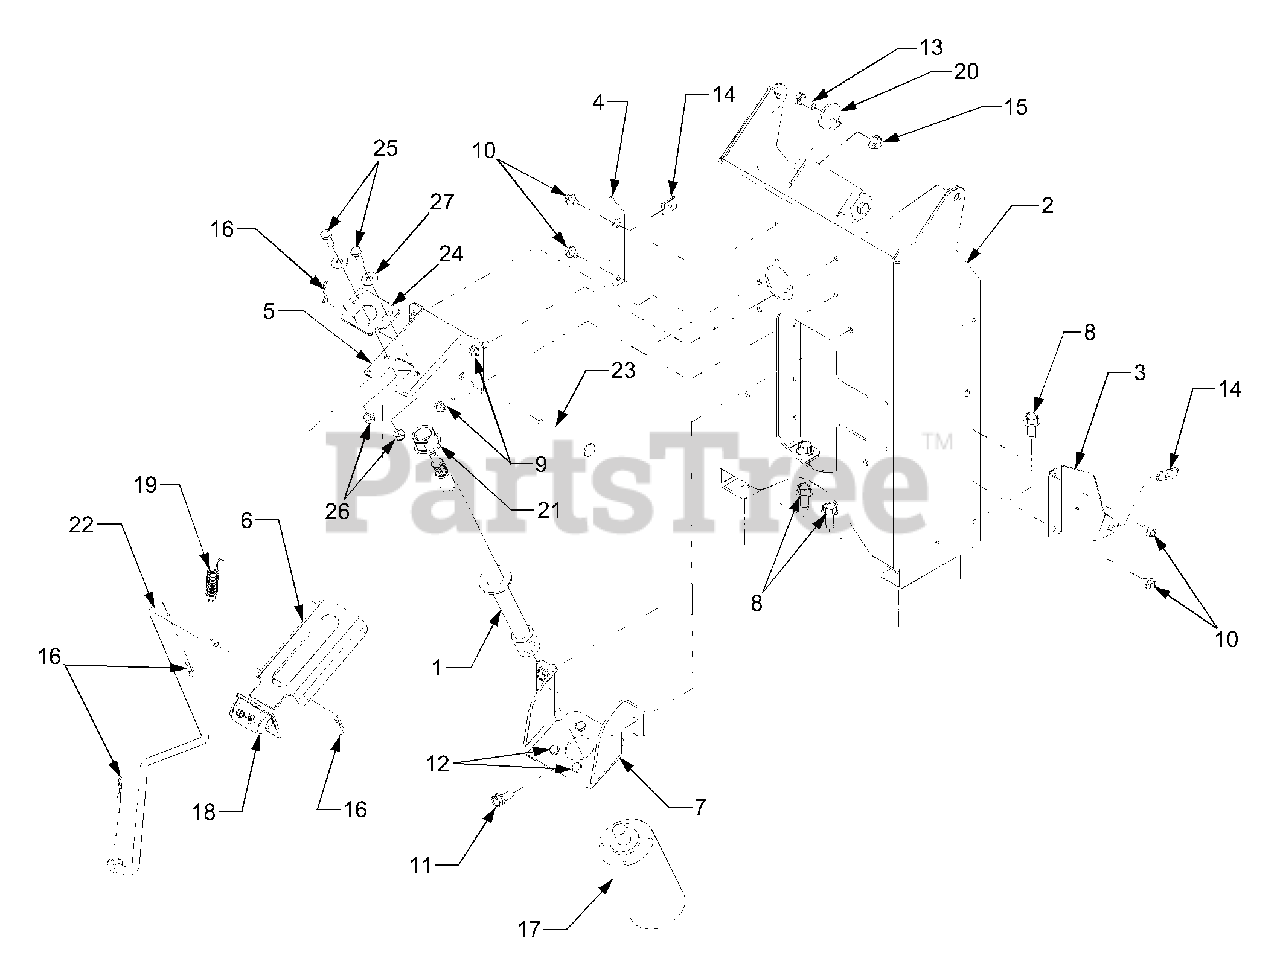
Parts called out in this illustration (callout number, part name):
1	Shaft, Steering
4	Bracket, Dash Mtg. LH
9	Screw, Hex Wash, Hd Tapp 1/4-20 x .75
10	Screw, Hex Wash, Hd Tapp 1/4-20 x .375
11	Screw, Hex Wash, Hd Tapp 5/16-18 x .75
12	Screw, Hex, M6-1 x 16 Hardened
13	Screw, Hex Cap 5/16-18 x .75 GR5
14	Nut, Speed, 1/4-20
15	Nut, Hex Flange Lock, 5/16-18
16	Pin, Internal Cotter
17	Pump, Hydraulic Steering
18	Lever, Parking Brake
19	Spring, Extension
20	Washer, Flat, .33 x 1.25 x .12
21	Bearing, Hex Flange, .75 ID
22	Rod, Parking Brake
23	Pin, Parking Brake Pivot
26	Nut, Hex Insert Lock, 1/4-20
27	Washer, Flat, .28 x .74 x .063
